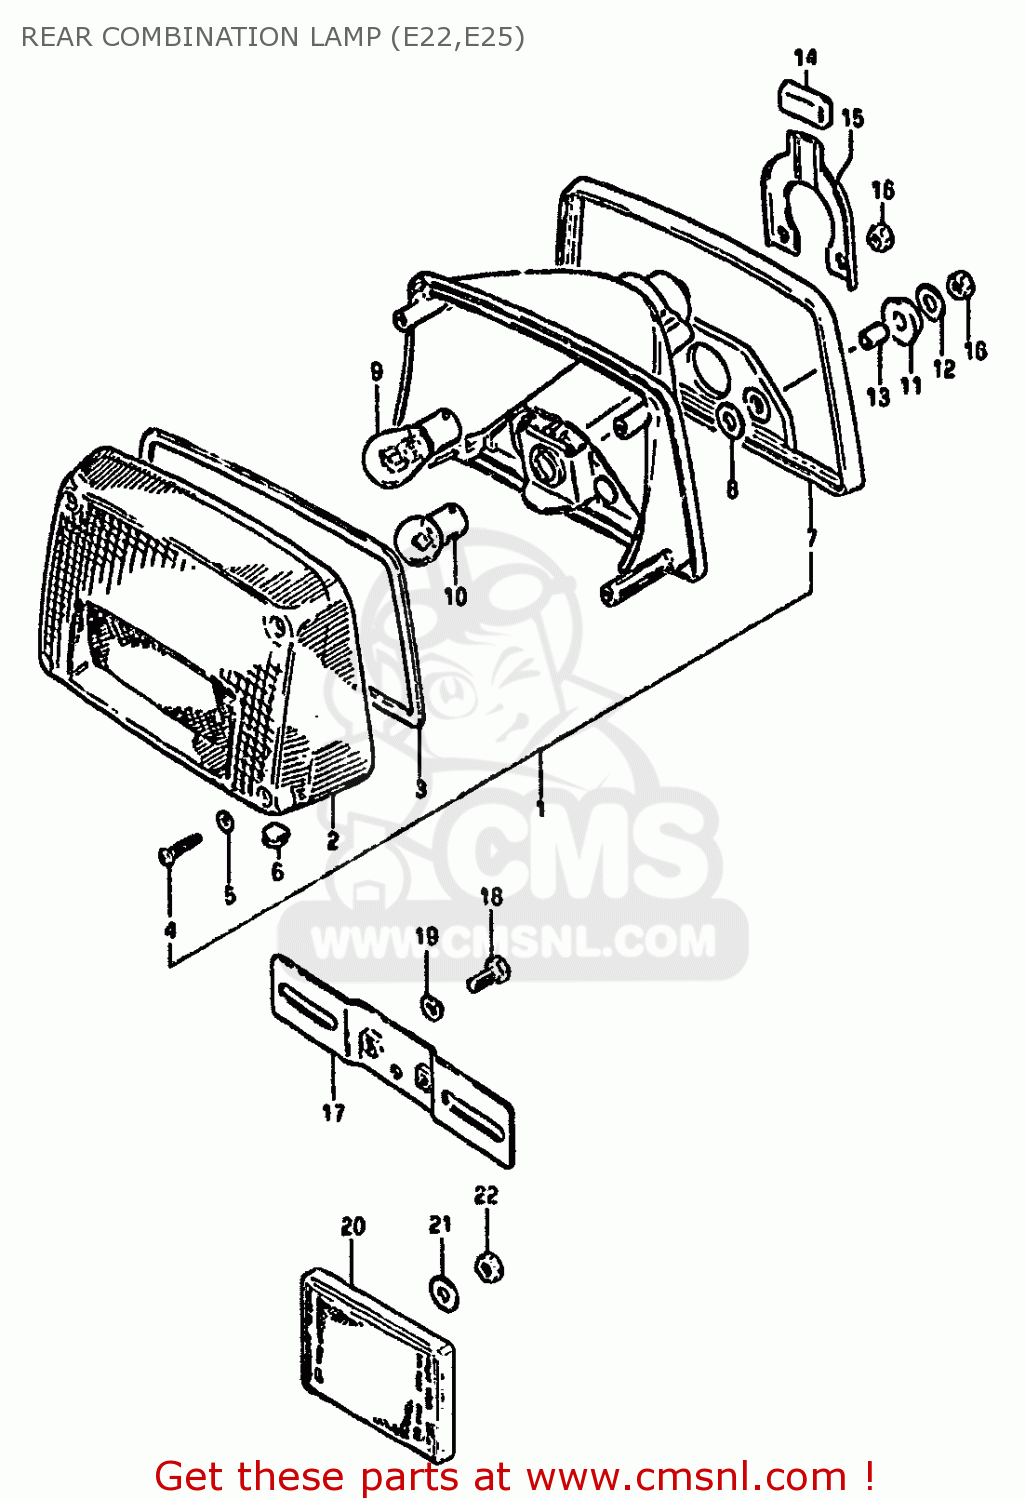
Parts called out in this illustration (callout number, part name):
1	LAMP,REAR COMBINATION
2	LENS
3	GASKET (NAS)
4	SCREW,REAR COMBINATION LAMP
5	GASKET (NAS)
6	GROMMET
7	CUSHION,REAR COMBINATION LAMP
8	WASHER,REAR COMBINATION LAMP
9	BULB(12V21/5W)
10	BULB(12V10W,TOKAI DENSO)
11	CUSHION,RR COMBINATION LAMP
12	WASHER
13	SPACER (6.4X9X10.5)
14	CUSHION,REAR COMBINATION LAMP
15	PLATE
16	NUT 6MM
17	BRACKET, LICENSE PLATE
18	BOLT
19	LOCK WASHER
20	REFLEX REFLECTOR,RR
21	WASHER(5.2X16X1)
22	NUT
